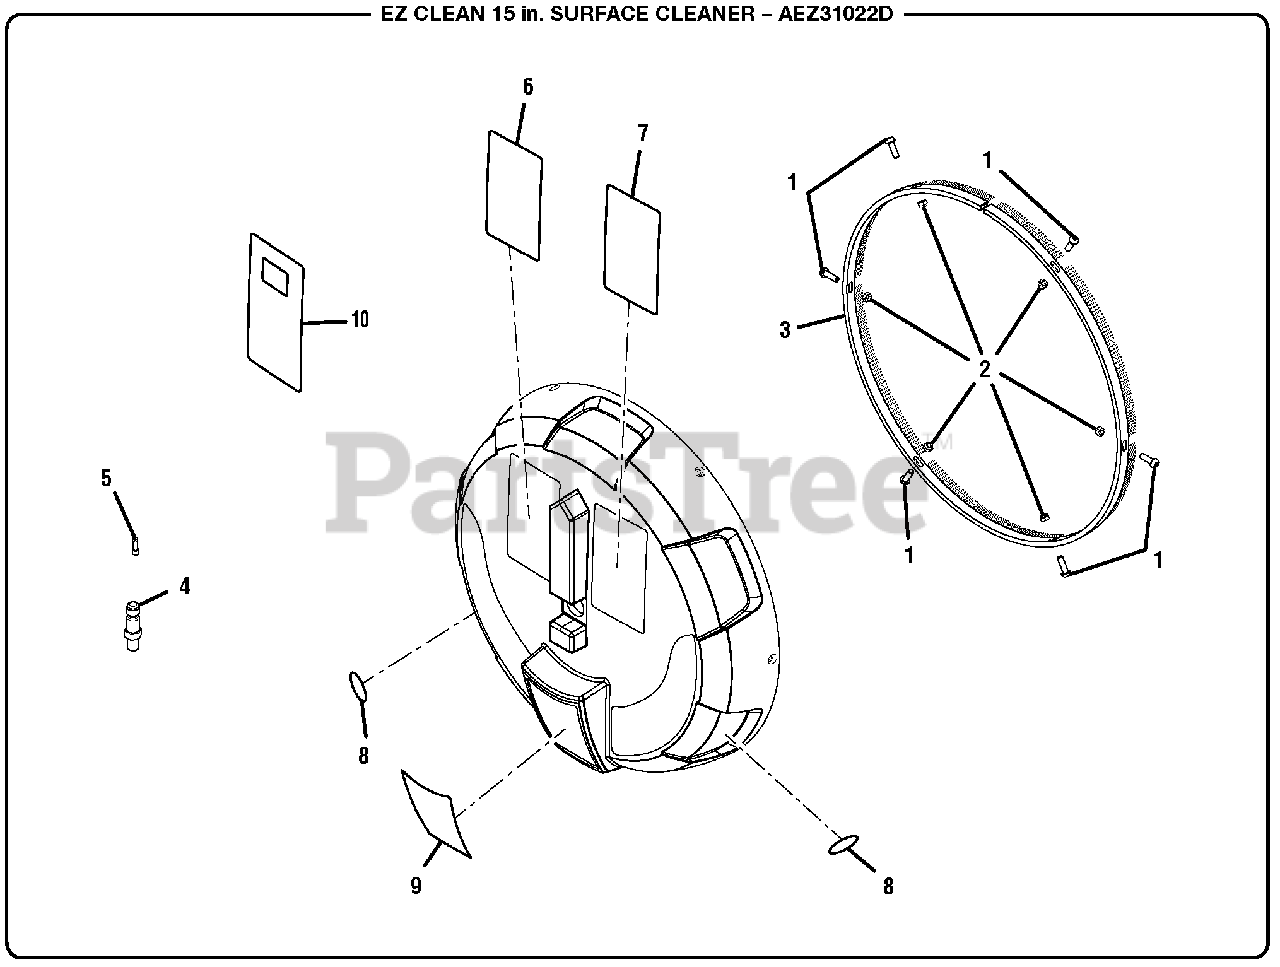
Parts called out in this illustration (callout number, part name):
1	Bolt (M5 x 16 mm, Pan Hd.)
2	Lock Nut (M5)
3	Deck Brush Skirt
4	1/8 in. Quick Connect
5	Inlet Filter
6	Danger Label
7	Danger Label (French)
8	No Hands Label
9	Logo Label
10	Hang Tag Danger Label
